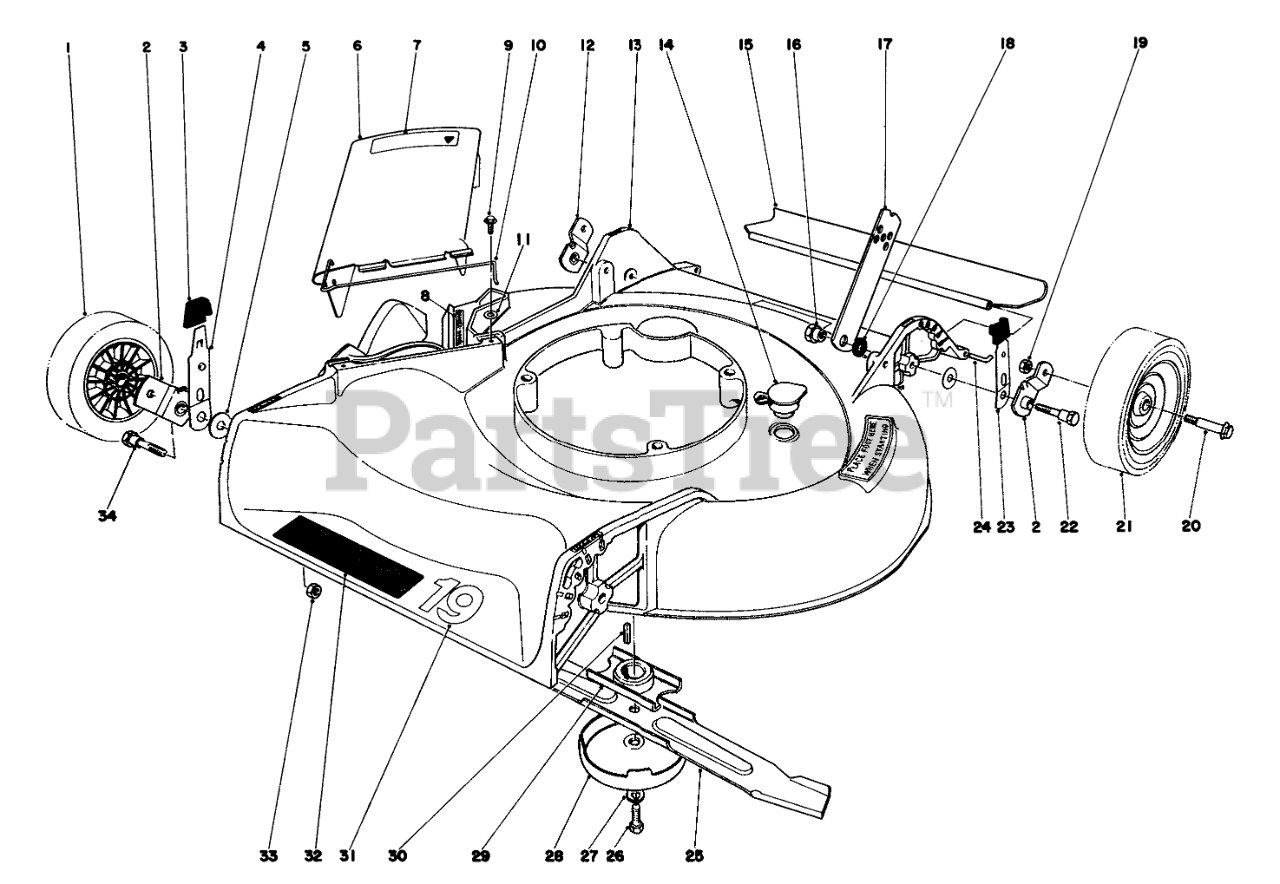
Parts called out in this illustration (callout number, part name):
1	Wheel Assembly
2	Pivot Arm
3	KNOB-ARM
4	SPRING ARM ASM
5	WASHER-PIVOT
6	Deflector-Cover Assembly (Incl. Ref. #7 & 10)
7	Caution Decal
8	Decal
9	SCREW
10	SPRING HINGE
11	WASHER-FLAT
12	Pivot Arm
13	Housing
14	WASHOUT PLUG
15	SHIELD - TRAILING
16	HANDLE PIVOT NUT
17	Handle Latch
18	HANDLE LATCH SPACER
19	Nut
21	Wheel Assembly
22	PIVOT SCREW
23	SPRING ARM ASM
24	SHIELD ROD
25	Blade
26	SPECIAL SCREW
27	WASHER-LOCK
28	AntiScalp Cup
29	Blade Retailer
30	KEY-SQUARE
31	Decal-19"
32	Decal-Deck
33	Nut
34	PIVOT SCREW
